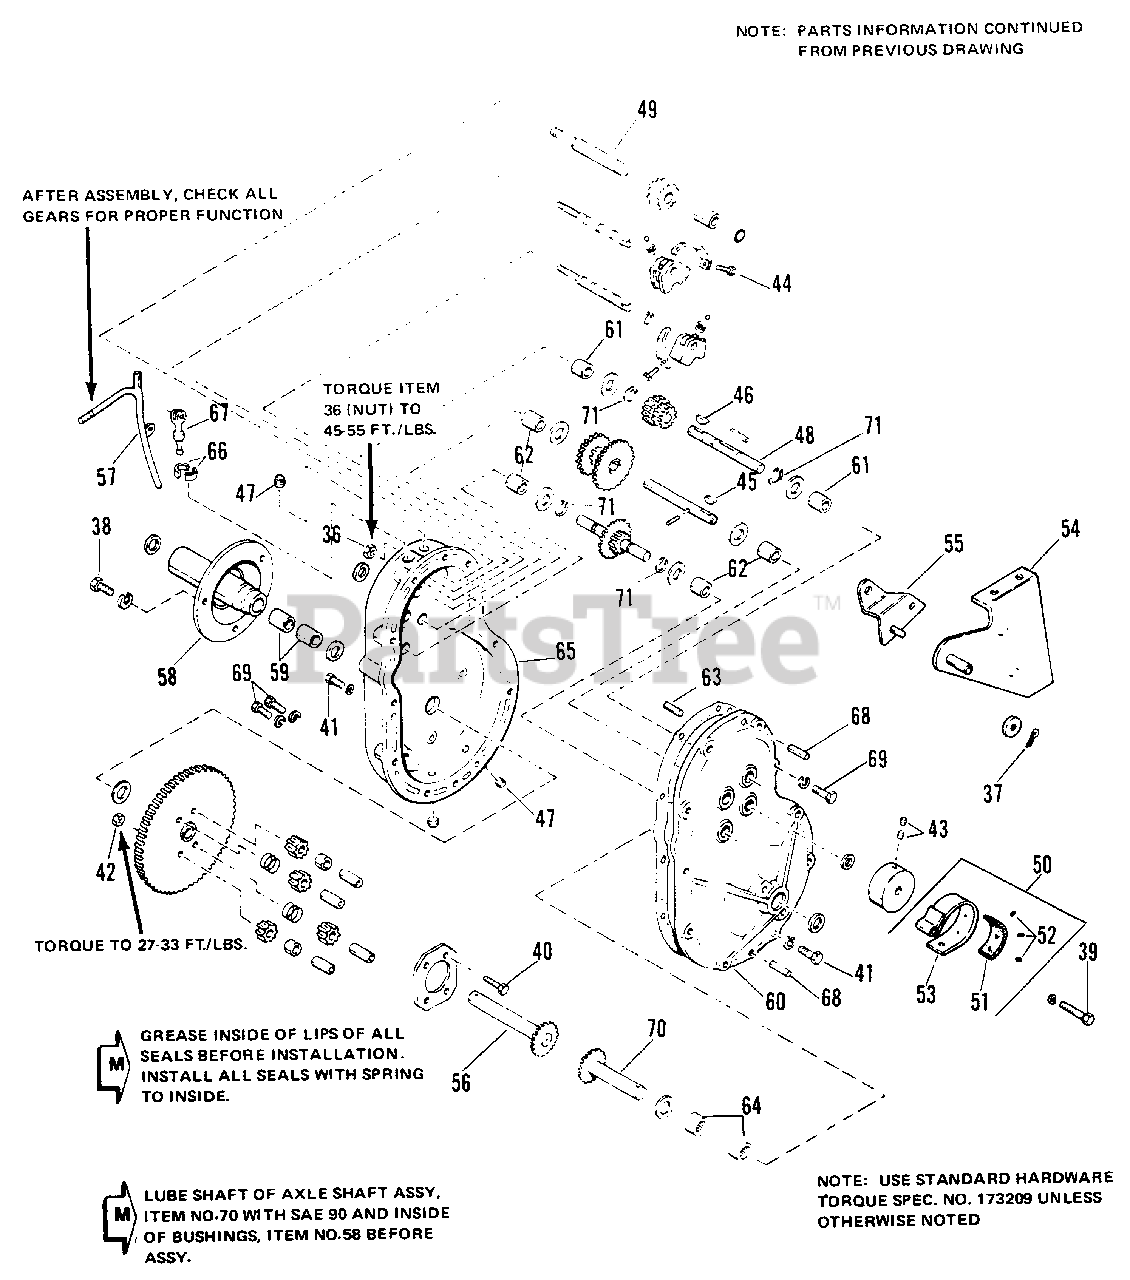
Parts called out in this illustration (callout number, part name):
36	NUT, Hex, 7/16-14
37	PIN, Cotter, 1/4 x 3/4
38	CAPSCREW, Hex Hd., 3/8-16 x 7/8
39	CAPSCREW, Hex Hd., 5/16-18 x 1-1/2
40	CAPSCREW, Hex Hd., 3/8-16 x 2-1/2
41	CAPSCREW, Hex Hd., 5/16-18 x 1-1/4
42	LOCKNUT, Hex, Full, 3/8-16
43	SCREW, Set Hex Skt., 5/16-18 x 5/16
44	SCREW, Hex Washer Hd., 5/16-18 x 5/16
45	KEY, Hi Pro, 5/32 x 5/8
46	KEY, Hi Pro, 3/16 x 3/4
47	PIPE, Bushing, 3/4
48	SHAFT, Input
49	SHAFT, Reverse Pinion
50	BAND ASSY, Brake
51	LINING, Brake
52	RIVET, Tubular, 3/16 x 1/4
53	BAND, Brake
54	SUPPORT ASSY, Transmission
55	IDLER LEVER ASSY
56	AXLE ASSY, R. H.
57	ROD ASSY, Shift
58	HOUSING ASSY, Axle w/Bearings
60	COVER, Sub-Assembly-Gear Case
62	BEARING, Roller
63	PIN, Sub- Assembly, Roll
64	BEARING, Roller
65	GEAR CASE SUB-ASSY
67	ROD ASSY, Shift
68	PIN, Spring, 3/8 x 1
69	CAPSCREW, Hex Hd., 3/8-16 x 3/4
70	AXLE ASSY, L. H.
71	RING, Retaining
